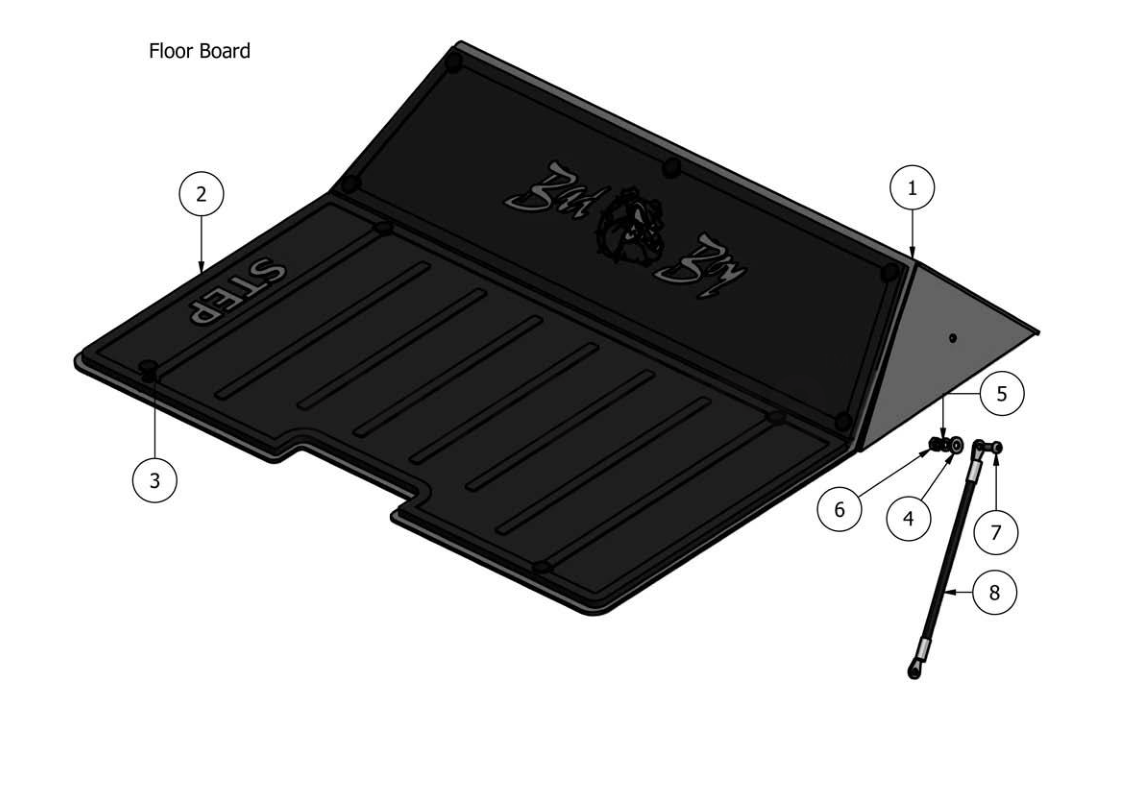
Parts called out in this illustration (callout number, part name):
1	Floor Panel
3	Ratchet Fastener
4	1/4" Flat Washer
5	1/4" Lock Washer
6	1/4" Hex Nut
7	1/4" x 5/8" Buttonhead Bolt
8	Floor Panel Cable
